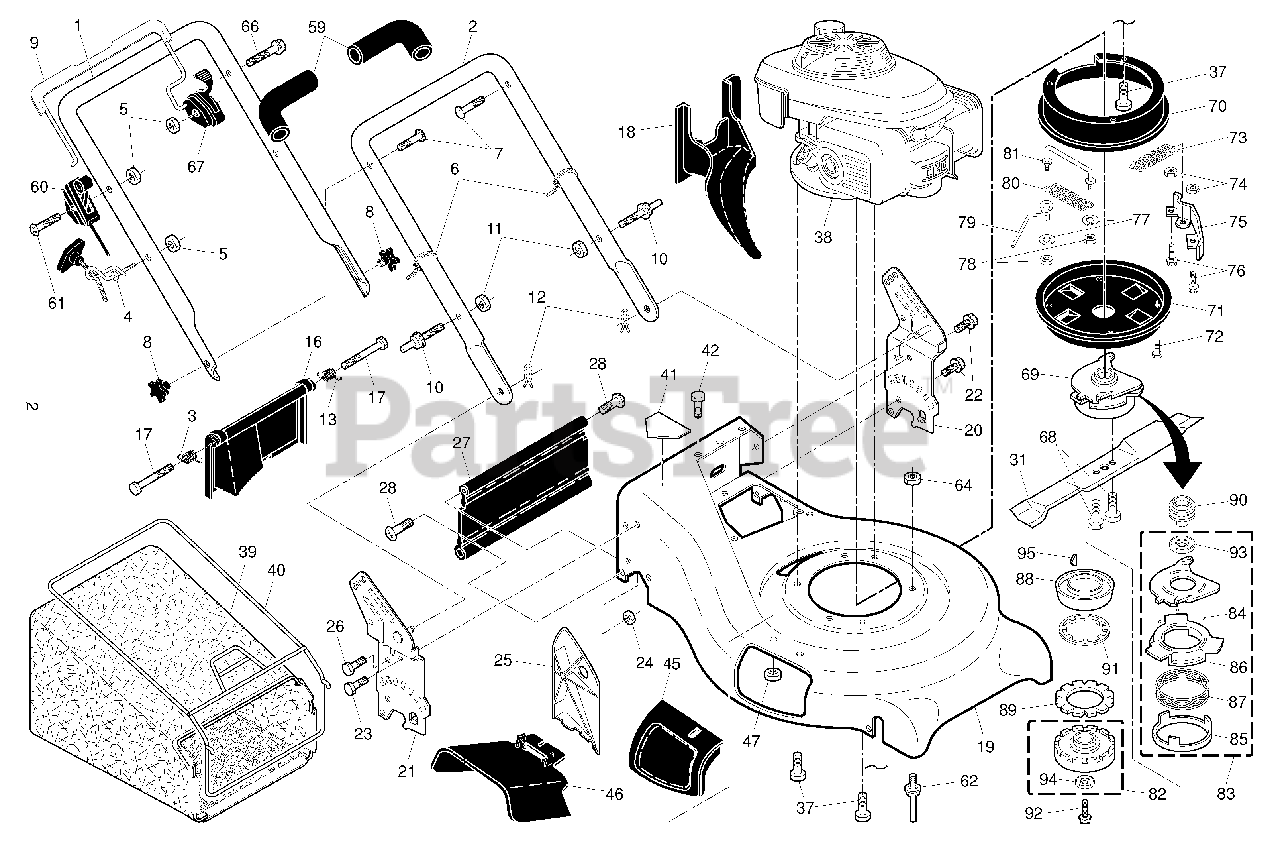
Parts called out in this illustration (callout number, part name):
1	Handle, Upper
2	Handle, Lower
3	Spring, Rear Door, RH
4	Guide, Rope, Side
5	Nut, Hex Lockwasher Insert 1/4-20
6	Wire, Tie
7	Bolt, Handle 5/16-18 x 1.75
8	Knob, Handle
9	Bar, Control, Auto-Walk
10	Bolt, Carriage
11	Nut, Hex, Centerlock 5/16-18 UNC
12	Cotter, Hairpin
13	Spring, Rear Door, LH
16	Rear Door Assembly
17	Bolt, Rear Door
18	Plug, Mulcher
19	Kit, Housing
20	Handle Bracket Assembly, LH
21	Handle Bracket Assembly, RH
22	Screw, Hex Washer Head
23	Bolt, Hex Head 5/16-18 x 5/8
24	Nut, Hex, with Lock Washer Insert 5/16-18
25	Baffle, Side
26	Screw 12 x 5/8
27	Skirt, Rear
28	Screw, Hinge 1/4-20 x 1.25
31	Blade, 21"
37	Bolt, Engine
39	Grassbag
40	Frame, Grassbag
41	Danger Decal
45	Mulcher Door Assembly
46	Deflector, Discharge
59	Grip, Handle, Foam, Smooth (one side)
60	Throttle / Engine Control
61	Screw, Hex Head 1/4-20 x 2-1/8
62	Belt Guide, Stud
64	Nut, Hex 3/8-16
66	Screw, Hex Washer Head 1/4-20 x 1/2
67	Blade Brake / Clutch Control
68	Bolt, Hex Head
69	Blade Brake / Clutch
70	Belt Cover, Upper
71	Belt Cover, Lower
72	Screw, Tapping, Hex Washer Head #10-24
74	Nut, Hex, Centerlock, Zinc Plated 1/4-20
75	Bracket
76	Bolt, Hex Cap Head 1/4-20 x 5/8
77	Washer, Flat
78	Nut, Hex 3/8-16
79	Belt Keeper
81	Link, Torque
82	Holder Assembly, Blade
83	Plate Assembly, Ball Control
84	Ball, Steel
85	Plate, Spring Hook
86	Plate, Brake
87	Spring, Ball Plate
88	Disk, Drive
89	Disk, Driven
90	Pulley, Drive
91	Spring, Clutch
92	Bolt, Flange (10 x 24)
93	Bearing, Radial Ball (6006)
94	Bearing, Radial Ball (6204)
95	Key, Woodruff (16 x 15)
